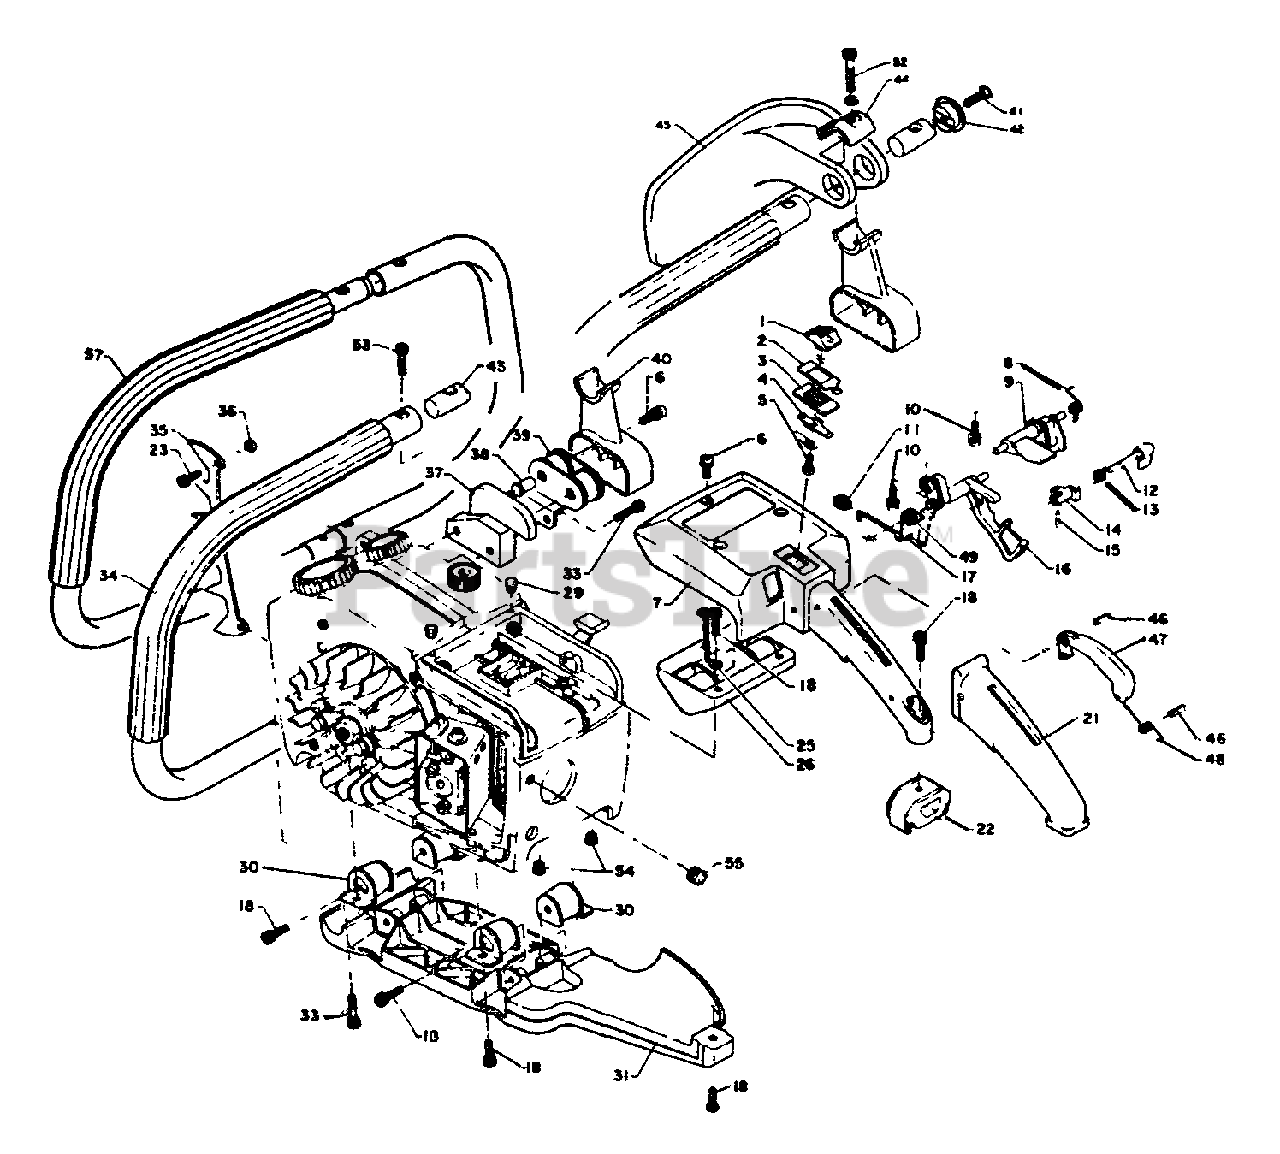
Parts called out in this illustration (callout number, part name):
1	KNOB, SWITCH
2	PLATE - GROUND
3	GUIDE, SWITCH
4	CONTACT, SWITCH
5	SCREW - 4X10
6	SCREW - 5X14
7	HANDLE - REAR
9	Push lever
10	SCREW - 4X14
12	LEVER, THROTTLE
13	SPRING, LOCKOUT LEVER
14	LOCKOUT, THROTTLE
15	PIN - SPRING -- 1.6X10
16	TRIGGER, THROTTLE
17	ROD, THROTTLE
18	SCREW - 5X14
21	COVER, HANDLE
22	CUSHION
23	SCREW - 5X12
25	LEAD - GROUND
26	CUSHION
29	CUSHION
30	CUSHION
31	BRACKET, HANDLE - LOWER
33	SCREW - 5X20
34	HANDLE - FRONT
35	SPIKE
36	LOCKNUT - 5
39	Cushion rubber (L-U)
40	BRACKET, HANDLE - UPPER
41	SCREW - 5X16
42	RETAINER, GUARD
45	GUARD
46	PIN - SPRING -- 4X16
47	LOCKOUT, THROTTLE
48	SPRING, LOCKOUT LEVER
49	SPRING, TRIGGER
52	SCREW - 5X35
53	SCREW - 5X25
55	PLUG
56	GUIDÃO LOOP, D
57	HANDLE, LOOP - LEFT
